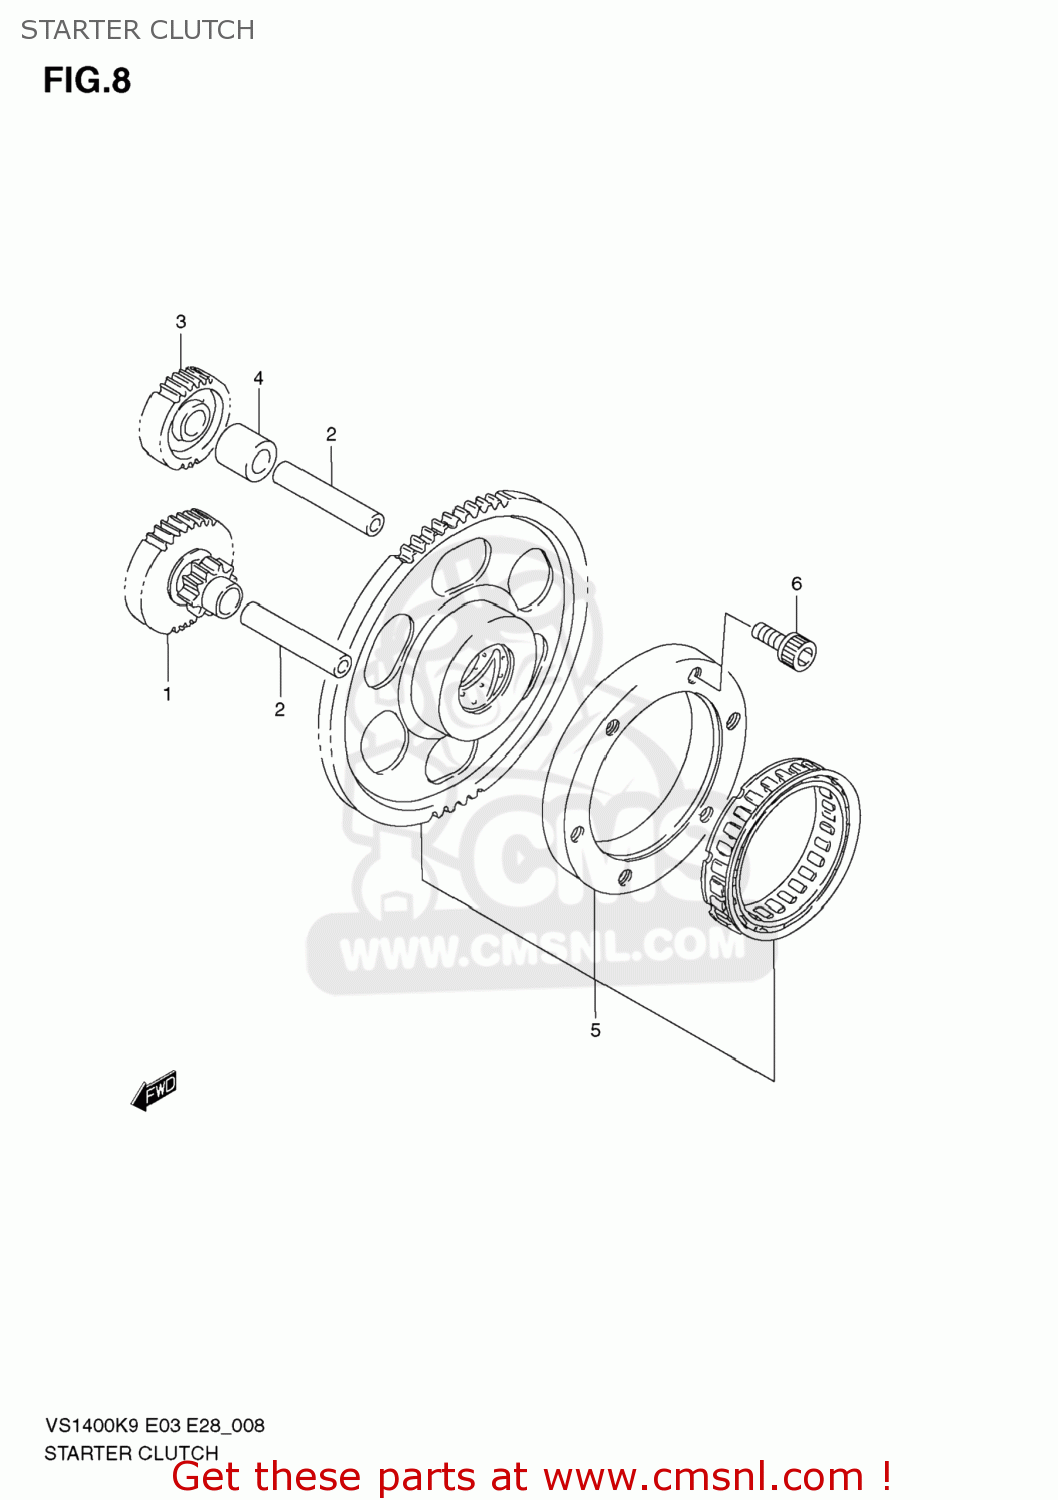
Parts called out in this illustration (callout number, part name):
1	GEAR,STARTER IDLE NO.1
2	PIN(7X11X55)
3	GEAR,STARTER IDLE NO.2
4	SPACER(11.2X17.5X22)
5	CLUTCH SET,STARTER
6	BOLT(8X16)
